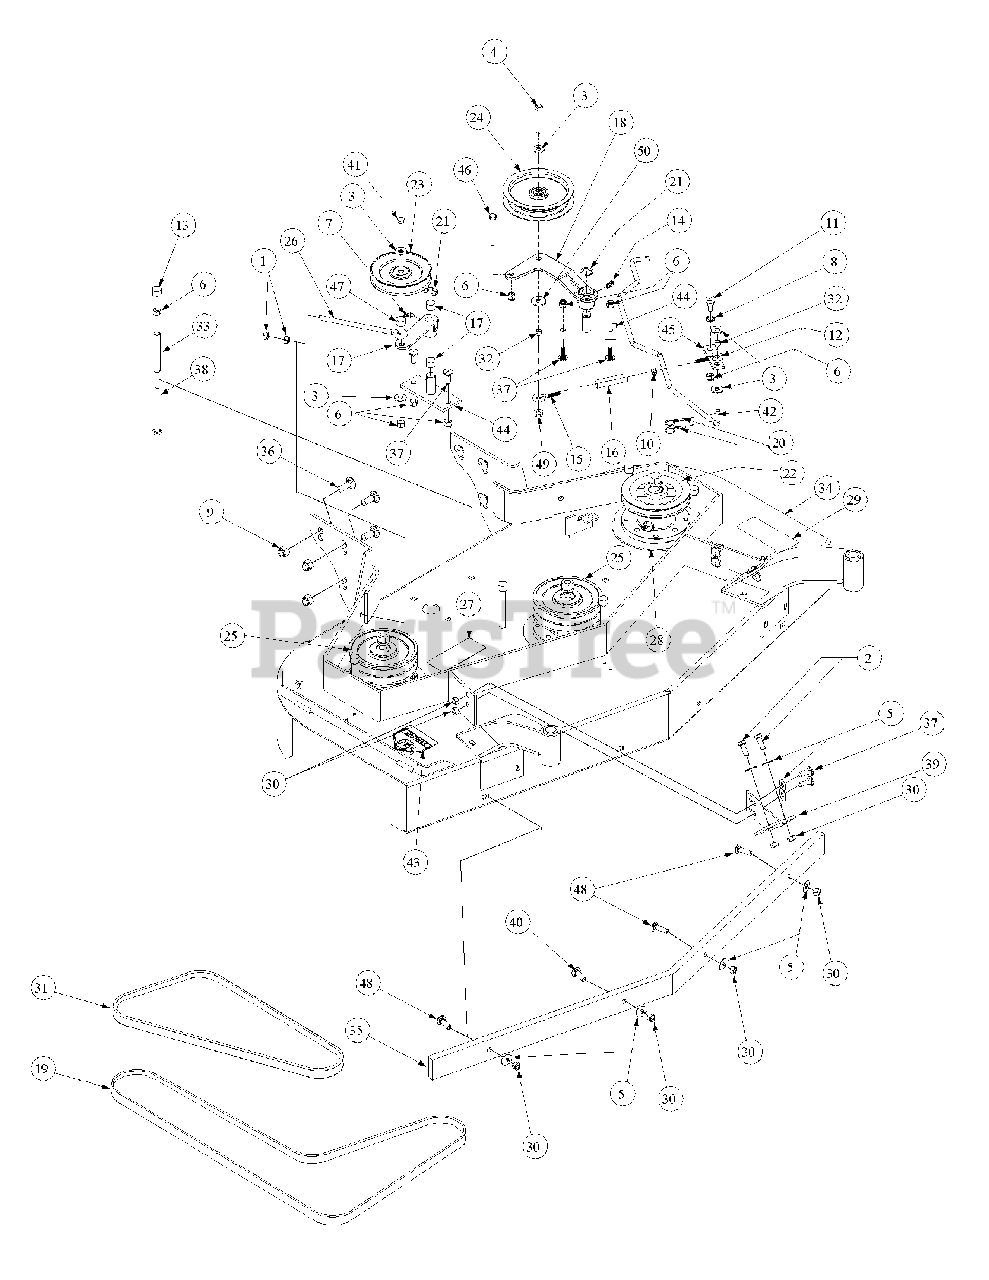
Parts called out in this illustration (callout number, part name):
1	Hex Nut, 3/8-16
2	Hex Cap Screw, 3/8-16, 1
3	Flat Washer, 3/8 Zinc
4	Hex Cap Screw, 3/8-16, 1
5	Flat Washer, 3/8 Zinc
6	Lock Nut, Nylon Insert, 3/8-16
7	Grease Fitting, 1/4-28, 90°
8	Shim Washer
9	Nut, Flange Lock, 1/2-13
10	Hex Nut, 5/16-18
11	Shoulder Bolt
12	Eye Bolt, Right Hand
13	Vinyl Cap
14	Grease Fitting, 45°, 1/4-28
15	Eye Bolt, Left Hand
16	Turnbuckle
17	Idler Arm "B"
18	Idler Arm "A"
19	Drive Belt
20	Hair Pin, 3/8"-1/2"
22	Deck Pulley
23	Idler Pulley
24	Idler Deck Take-up
25	Double Pulley
26	Rod Belt Tensioner
27	Decal Rotating Blade
28	Spindle Backing Plate
29	Decal Warning Shield Missing
30	Lock Nut, Metal, 3/8-16
31	Drive Belt
32	Sleve Turnbuckle
33	Spacer Belt Guide
34	Deck Weldment Mower
36	Carriage Bolt, 1/2-13 x 1-1/4
37	Carriage Bolt, 3/8-16 x 1
38	Carriage Bolt, 3/8-16 x 4-1/2
39	Caster Support Assembly
40	Carriage Screw, 3/8-16 x 1-1/2
41	Hex Cap Screw, 3/8-16, 2.25
42	Rod Clutch Link
43	Decal, Danger Hands and Feet
44	Idler Base
46	Hex Cap Screw, 3/8-16, 2.75
47	Sleeve Tensioner
48	Carriage Screw, 3/8-16 x 1-1/4
49	Hex Nut Flange Lock, 3/8-16
50	Washer, 1.25 x .411 x .100
